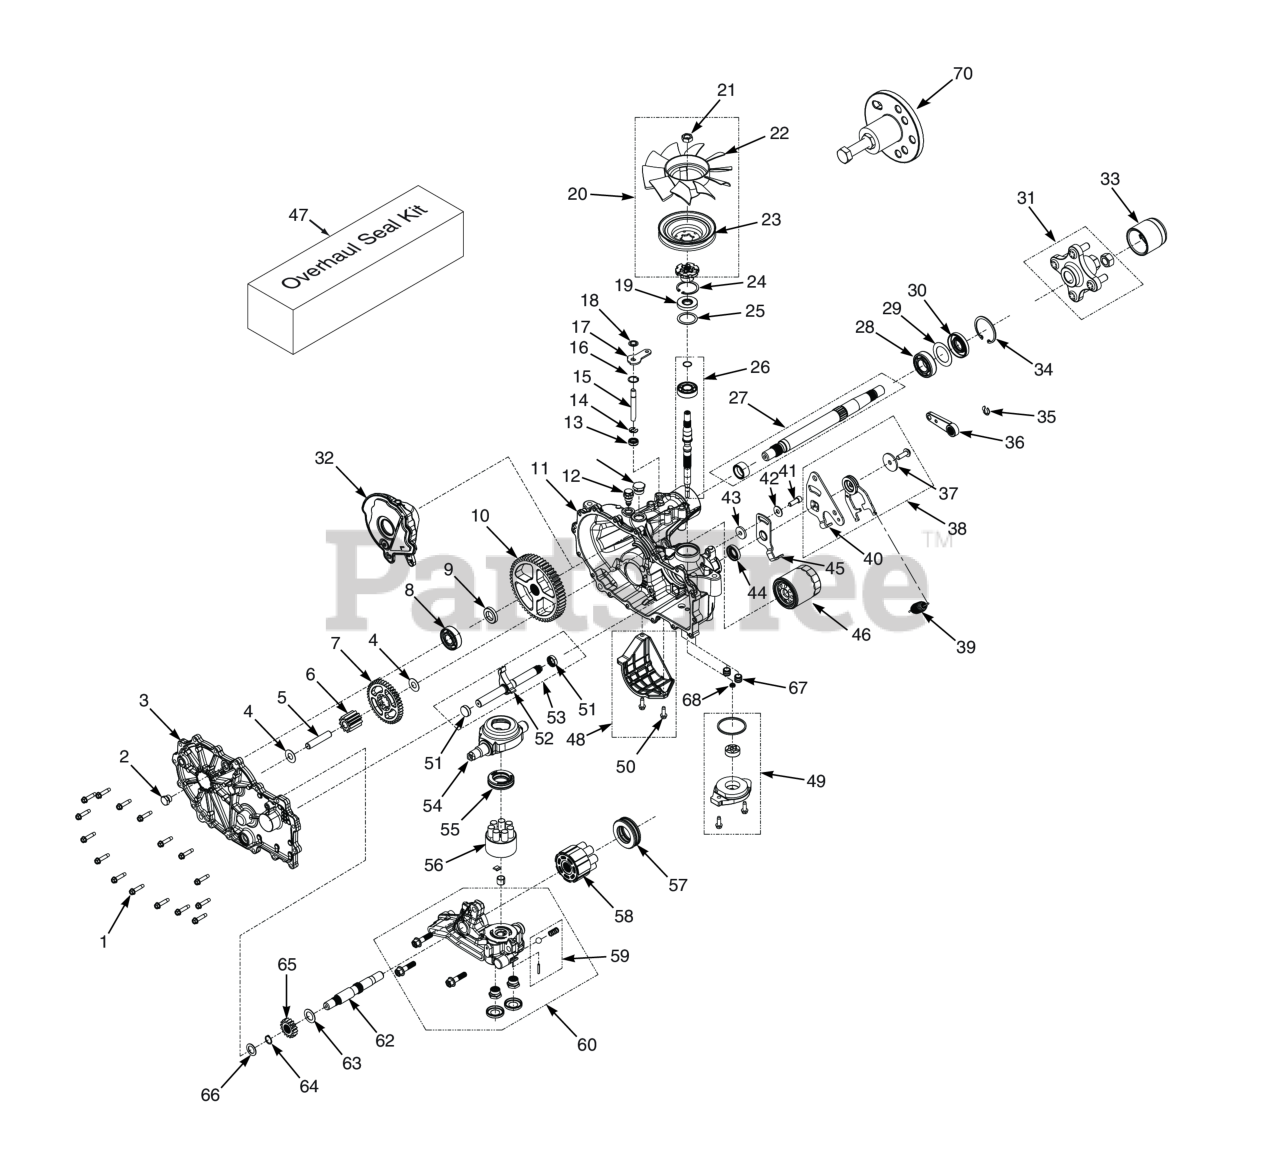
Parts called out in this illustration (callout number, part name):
1	Bolt, Hex Head 1/4-20 x 1-1/8"
2	Plug, External Hex Vent 9/16-18
3	Kit, Side Cover LH
4	Washer, .5 x 1.0 x .03
5	Jackshaft Pin
6	Gear, 11T
7	Gear, 43T
8	Kit, Bearing
9	Spacer, .750 x 1.320 x .257
10	Gear, 54T
11	Kit, Main Housing LH, Charge, Control
12	Fitting, Transmission - SFZ61
13	Seal, Lip .375 x .75 x .25
14	Ring, .Retaining .375 External
15	Rod, By-Pass
16	R i n g , Retaining .750 Internal
17	Arm, By-Pass
18	Ring, Retainging .375 External
19	Seal, Lip 17 x 40 x 7
20	Kit, Fan/Pulley
21	Nut, Hex Locking 1/2-20
23	Pulley
24	R i n g , Retaining 2.06 Internal
25	Washer, 1.23 x 1.56 x .04
26	Kit, Input Shaft
27	Kit, Shaft, Axle
28	Bearing, Ball 1.0 x 52 x 15 Open
29	Spacer, 1.355 x 2.035 x .021
30	Seal, Lip TC4 1.0 x 2.06 x .38
31	Hub Kit
32	Fitting 9 /16 - 18, Breather
33	Cap, Axle
34	R i n g , Retaining 2.06 Internal
35	Ring, Retaining External .375"
36	Handle, Brake
37	Washer, .343 x 1.5 x .062
38	Kit, RTN Assembly
39	Spring, RTN
40	Arm, Control
41	Bolt, Hex Head Cap Screw 5/16-24 x 1" Patch
42	Washer, 7/16 x 7/8 OD x .06 HT
43	Spacer, .32 ID x 1.005 OD x .1495 Thk
44	Seal, Lip 18 x 32 x 7
45	Arm, Neutral
46	Filter, Oil
47	Kit, Seal (ZT-2800)
48	Kit, Filter Guard (LH)
49	Kit, Charge Pump
50	Bolt, 1/4-20 x 3/4"
51	O-Ring, -111 x .103 x 424
52	Pawl, Brake
53	Kit, Outboard, RH Rot B / LH Rot A (LH)
54	Trunnion, Swashplate
55	Ball Thrust Bearing
56	Kit, Cylinder Block
57	Thrust Ball Bearing Assembly
58	Kit, 16cc Cylinder Block Assembly (steam
59	Kit, Charge Relief
60	Kit, Center Section
61	Screw, Hex Flange Head 3/8-16 x 1-1/2"
62	Shaft, Motor
63	Washer, .72 x 1.16 x .04
64	Ring, Retaining .625
65	Gear, 16T
66	Washer, HT .62 ID x 1.0 OD x .05 Thick
67	Tube, Charge Triple O-ring
68	Kit, Gerotor Seal
69	Plug, 3/4-16
70	Kit, Hub Puller
